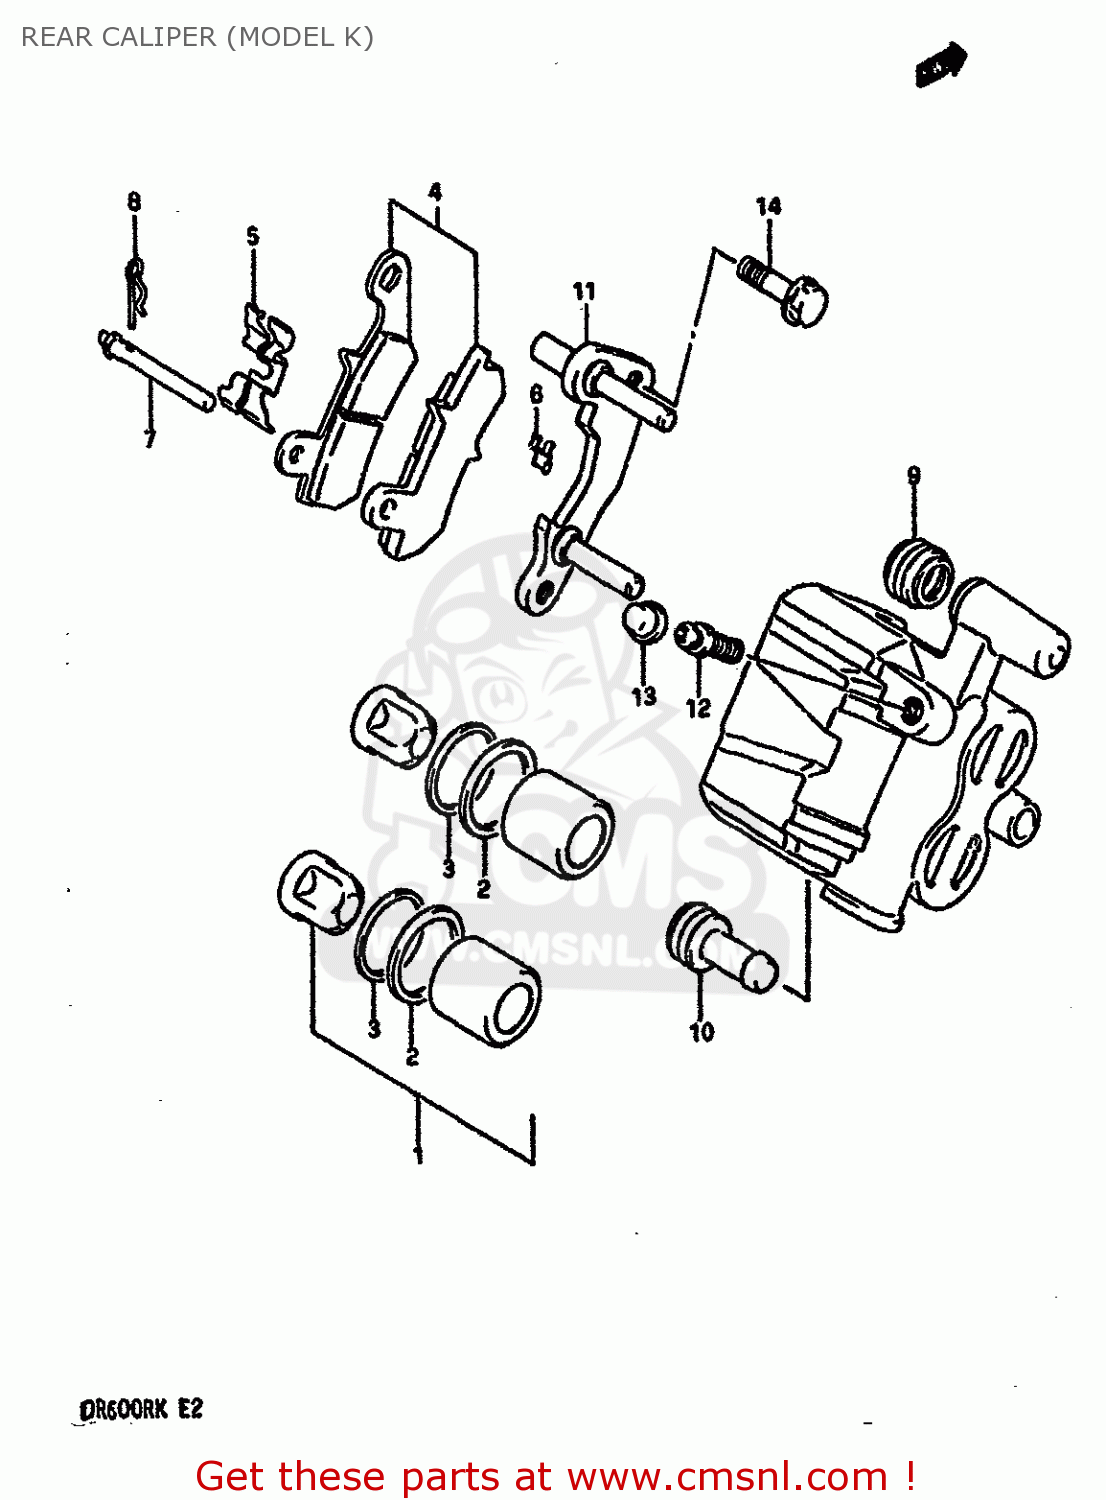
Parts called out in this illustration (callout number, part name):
1	BRAKE PISTON SET
2	SEAL,PISTON
3	SEAL,WIPER
4	PAD SET (NAS)
5	SPRING,PAD
6	GUIDE,PAD
7	PIN,PAD
8	CLIP,PAD PIN
9	BOOT,AXLE
10	INSULATOR,AXLE
11	CARRIER
12	BLEEDER
13	CAP,BREATHER
14	BOLT L:21
